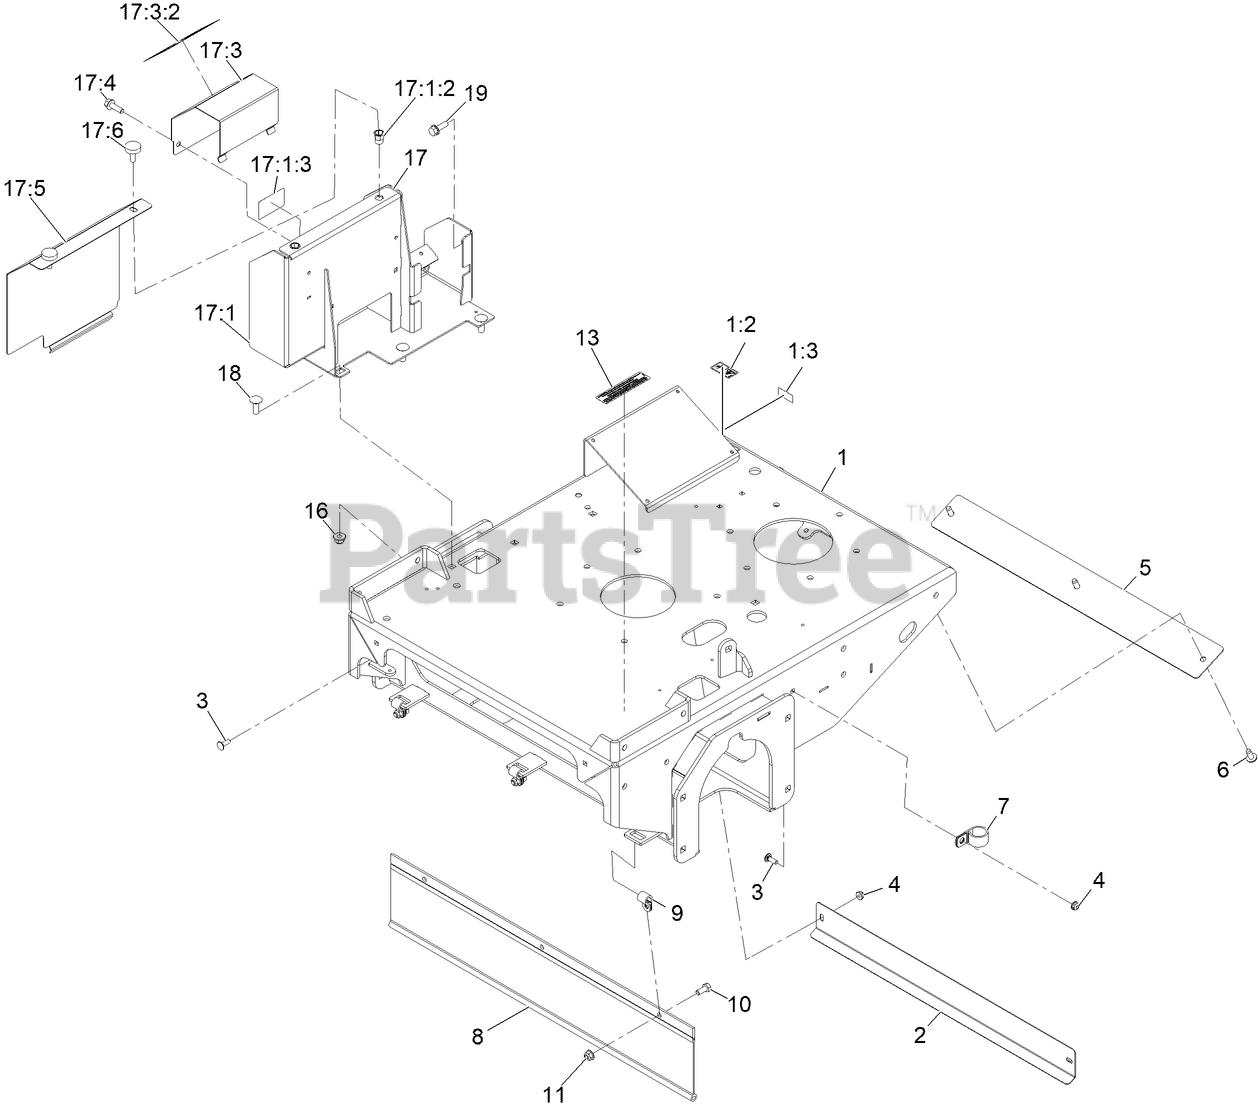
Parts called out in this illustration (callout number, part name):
1	ENGINE DECK ASM
1:2	DECAL-SHOCK HAZARD
1:3	DECAL-DANGER
2	GUARD-LOWER
3	BOLT-CARR
5	PANEL-BOTTOM
7	CLIP-LOOM
8	SHIELD,DRAG
9	CLIP-LOOM
10	SCREW-HH
11	NUT-HF, NI
13	DECAL-ARRESTOR, SPARK
16	NUT-HF, NI
17	Bracket ASM-Controller
17:1	ASM-ELEC HOUSING
17:1:2	Nut-Clinch
17:1:3	DECAL-FUSE,MAIN
17:3	ASM- RELAY COVER
17:3:2	DECAL-SERVICE AID
17:4	SCREW-HHF
17:5	COVER- HOUSING
17:6	SCREW-THUMB
18	SCREW-CARR
19	SCREW-HHF
